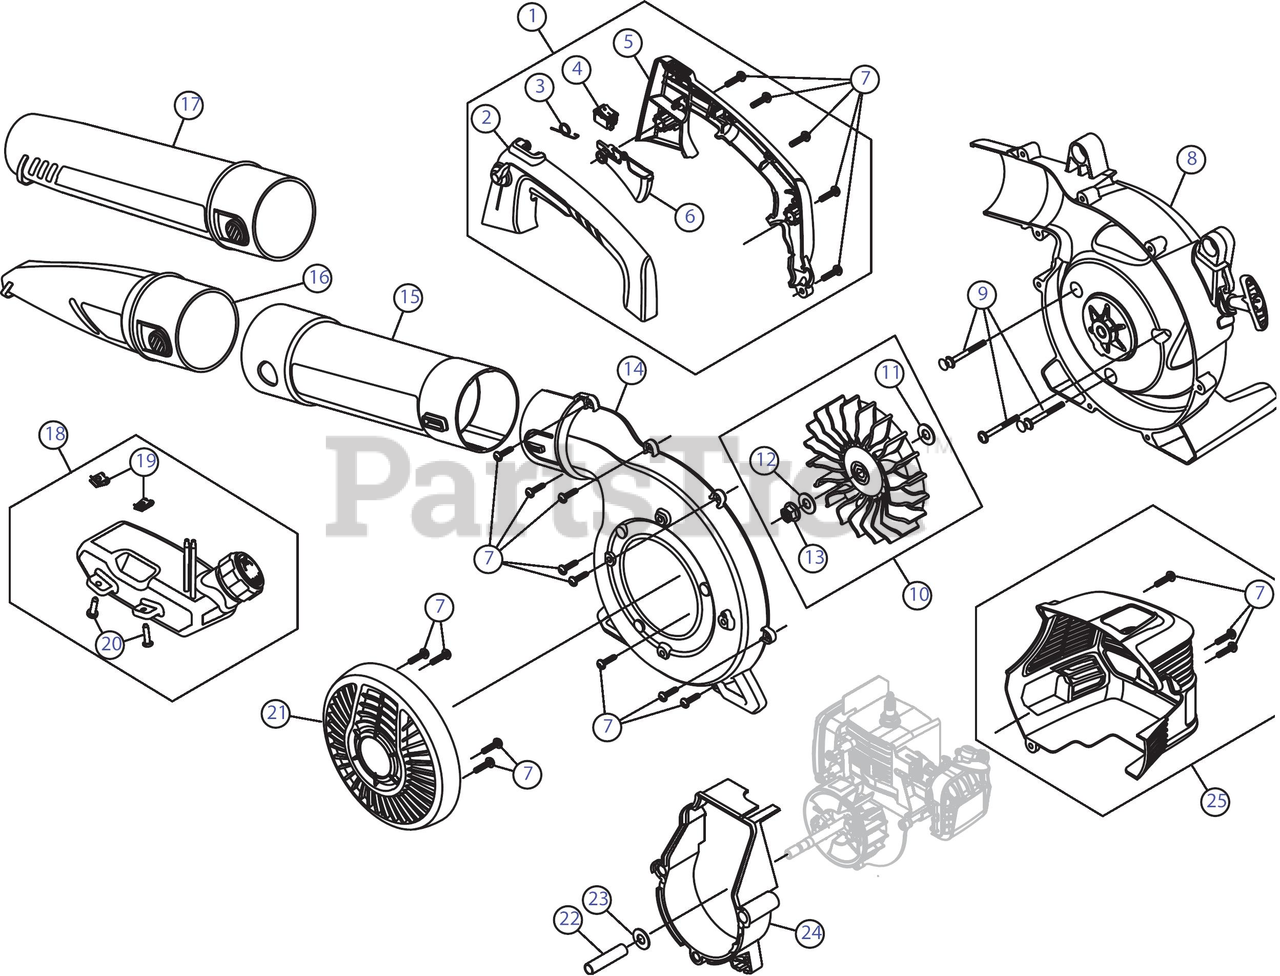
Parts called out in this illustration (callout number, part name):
1	Handle Assembly
2	Handle (LH)
3	Trigger Spring
4	On/Off Switch
5	Handle (RH)
6	Throttle Trigger
8	Impeller Housing Assembly (RH) (Incl. 9)
10	Impeller Assembly
11	Washer
12	Lock Washer
14	Impeller Housing Assembly (LH) (Incl. 7)
15	Upper Blower Tube
16	Blower Nozzle
17	Lower Blower Tube
18	Fuel Tank Assembly
19	U-Shaped Nut
21	Intake Cover (Incl. 7)
22	Shaft Spacer
23	Washer
24	Engine Adapter (Incl. 9)
25	Engine Cover Housing (Incl. 7)
